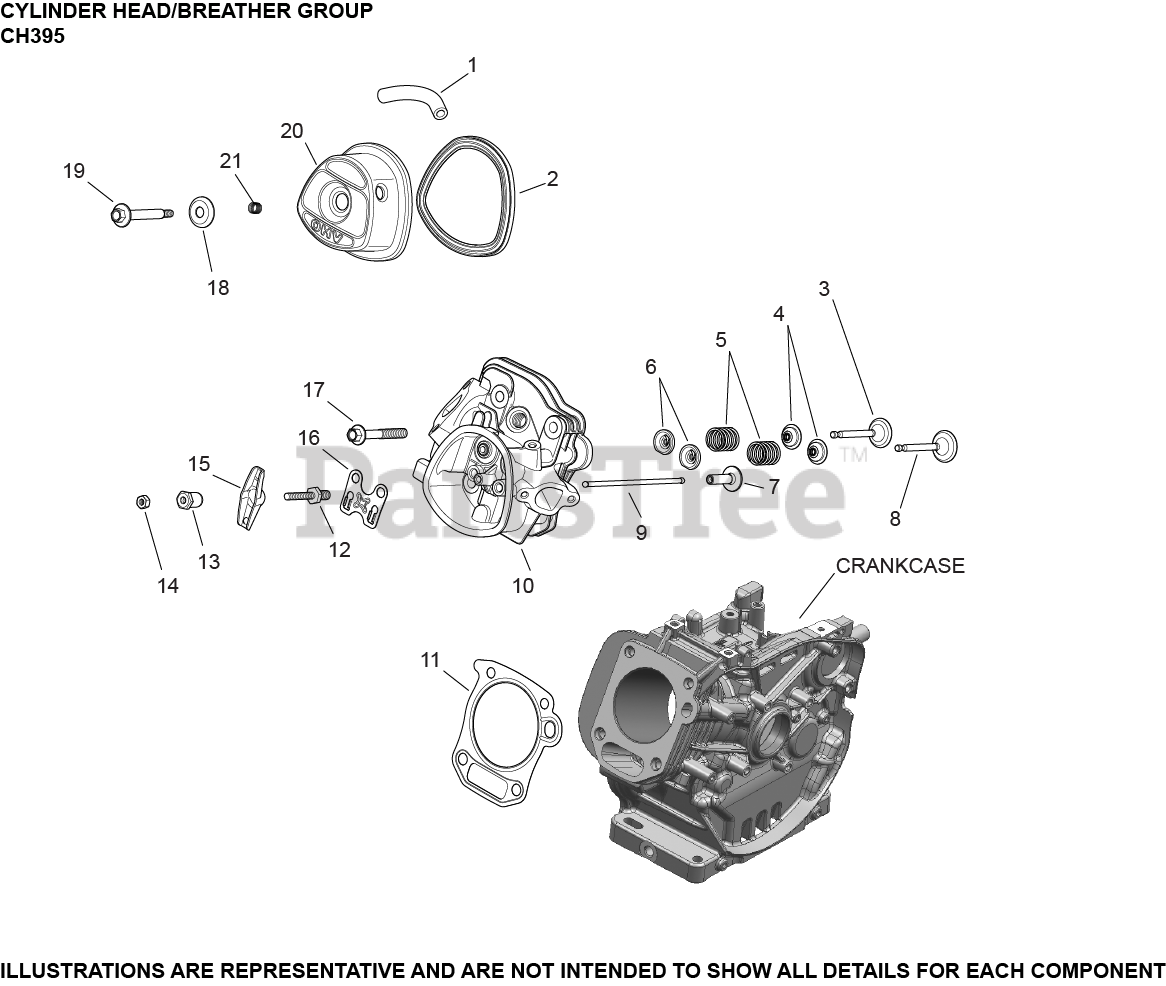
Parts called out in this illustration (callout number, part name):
1	TUBE, BREATHER
2	GASKET, VALVE COVER
3	VALVE, EXHAUST
4	SEAL, VALVE STEM
5	SPRING, VALVE
6	RETAINER, VALVE SPRING
7	LIFTER, VALVE
8	VALVE, INTAKE
9	PUSH ROD
10	KIT, CYLINDER HEAD
11	KIT, HEAD GASKET
12	STUD, ROCKER ARM - (#1407222S)
13	PIVOT, ROCKER ARM
14	NUT, HEX JAM
15	ARM, ROCKER
16	PLATE, PUSHROD GUIDE
17	SCREW, HEX FLANGE CYLINDER HEAD (CKY)
19	SCREW, VALVE COVER SEAL ASSY
20	KIT, VALVE COVER ASSEMBLY
